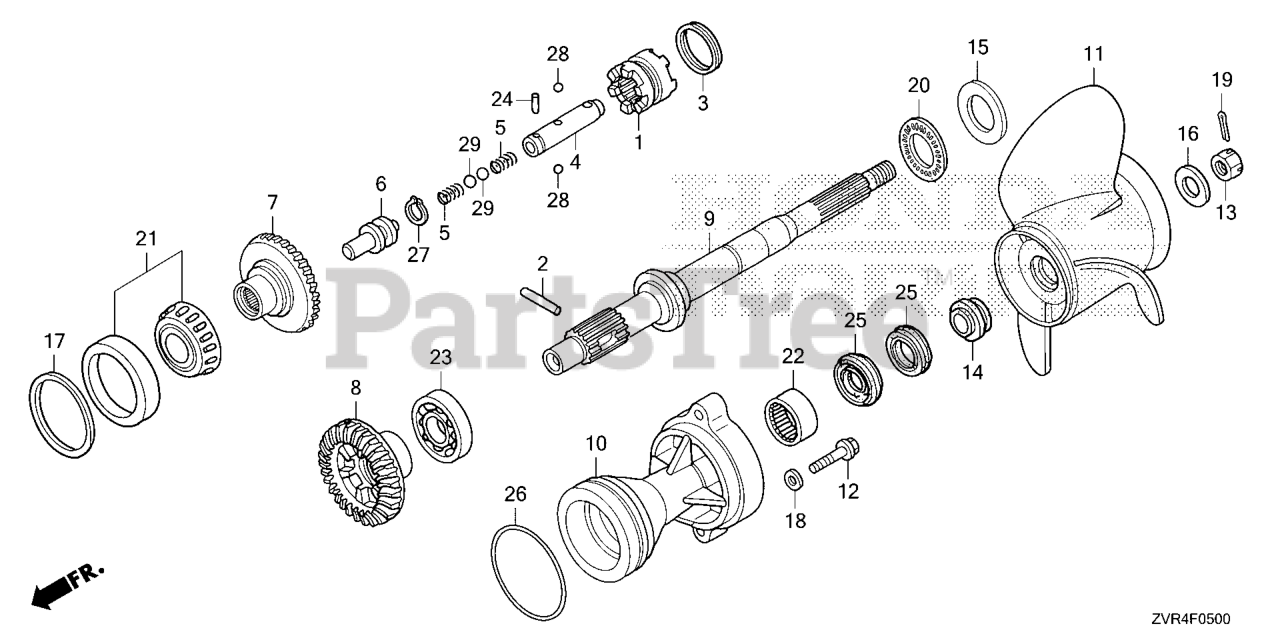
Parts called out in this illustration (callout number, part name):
1	SHIFTER, CLUTCH
2	PIN, SHIFTER (8X47)
3	RING, CROSS PIN
4	SLIDER, SHIFT
5	SPRING, SHIFT
6	PLATE, SHIFT
7	GEAR COMP, BEVEL F
8	GEAR, BEVEL (RVS. 30T)
9	SHAFT, PROPELLER
10	HOLDER, PROPELLER SHAFT *NHB14M* (AQUA MARINE SILVER METALLIC)
10	HOLDER,PROP*NH565*
11	PROPELLER, THREE-BLADE (15-1/2X13) *NH283* (AL) (STIN GRAY)
11	PROPELLER, THREE-BLADE (15-1/4X15) *NH283* (AL) (STIN GRAY)
11	PROP (15X17) *NH283*
11	PROPELLER, THREE-BLADE (14-3/4X19) *NH283* (AL) (STIN GRAY)
11	PROPELLER, THREE-BLADE (14-1/2X21) *NH283* (AL) (STIN GRAY)
11	PROPELLER, THREE-BLADE (14-1/4X23) *NH283* (AL) (STIN GRAY)
11	PROPELLER, THREE-BLADE (14-1/2X15) (SUS)
11	PROPELLER, THREE-BLADE (14-1/4X17) (SUS)
11	PROPELLER, THREE-BLADE (14X19) (SUS)
11	PROPELLER, THREE-BLADE (14X21) (SUS)
11	PROPELLER, THREE-BLADE (14-1/2X23) (SUS)
11	PROPELLER, THREE-BLADE (14X25) (SUS)
12	BOLT, FLANGE (10X40)
13	NUT, CASTLE (18MM)
14	WASHER, PROPELLER THRUST
15	WASHER, THRUST BEARING
16	WASHER, PROPELLER
17	SHIM A, BEVEL (0.10)
17	SHIM B, BEVEL (0.15)
17	SHIM C, BEVEL (0.30)
17	SHIM D, BEVEL (0.50)
18	WASHER, PLAIN (10MM)
19	PIN, SPLIT (4.0)
20	BEARING, THRUST (F)
21	BEARING, TAPER (50X90X28)
22	BEARING (30X37X26)
23	BEARING, RADIAL BALL (50X90X20)
24	ROLLER (3X12.8)
25	SEAL, WATER (30X45X7)
26	O-RING (105X3.1)
27	CIRCLIP (OUTER) (14MM)
28	BALL, STEEL (#7) (7/32)
29	BALL, STEEL (#9) (9/32)
